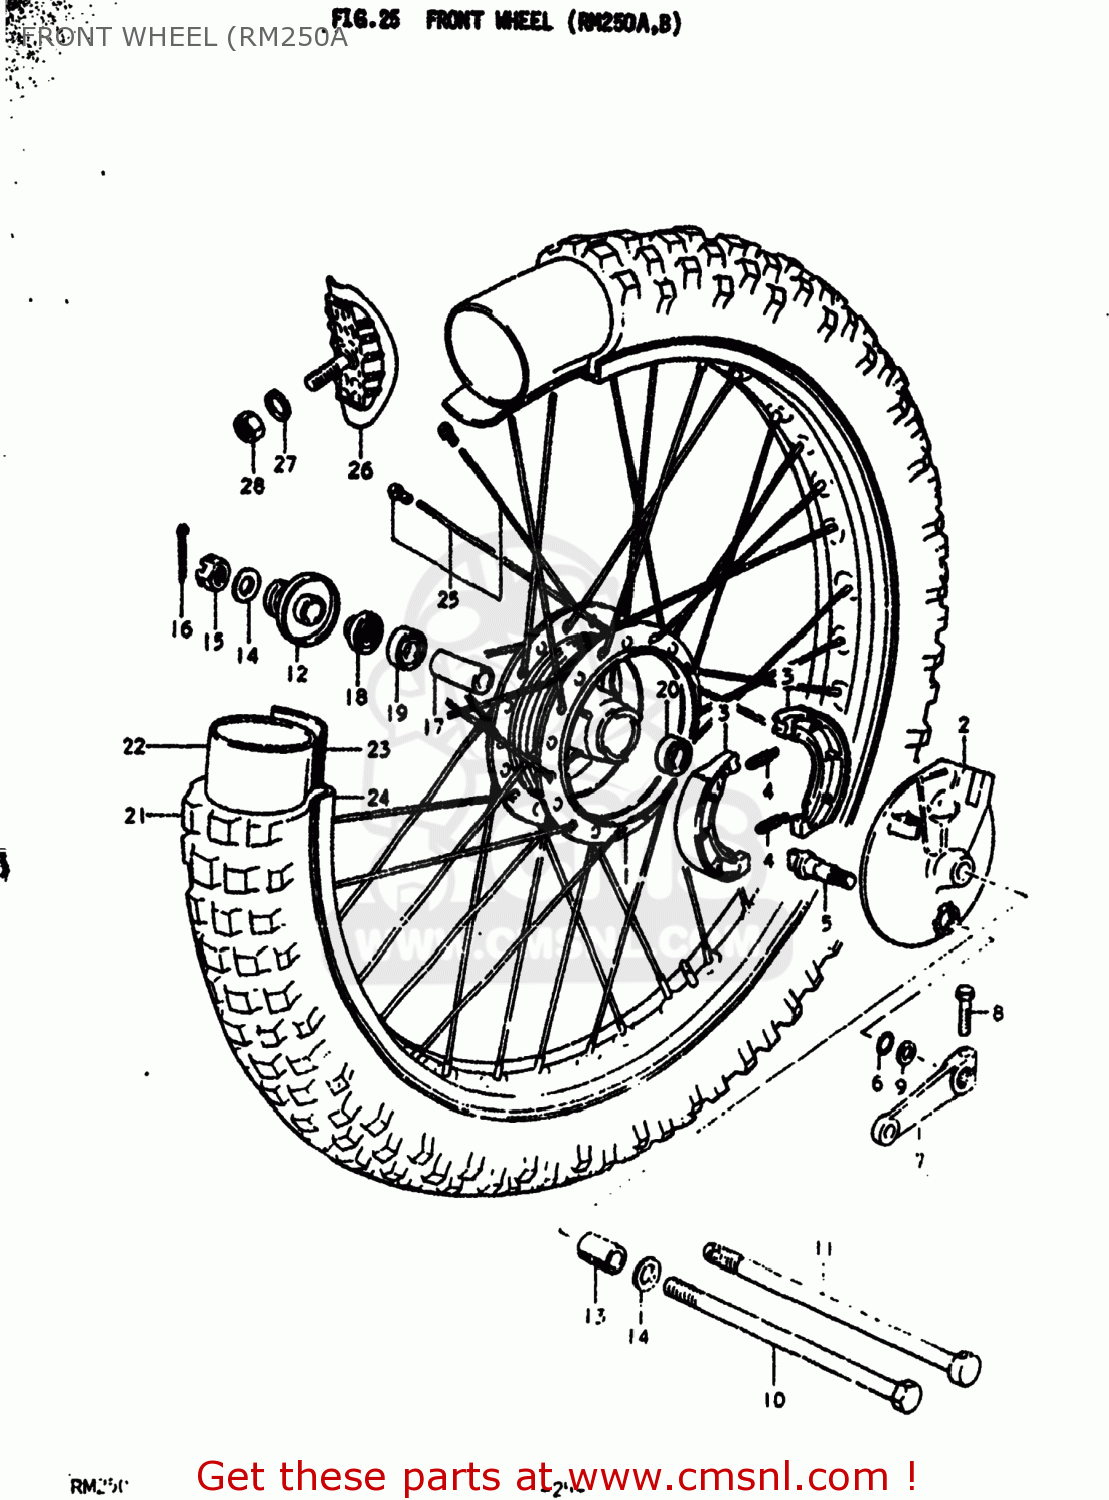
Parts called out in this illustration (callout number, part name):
1	HUB,FRONT
2	PANEL,FRONT HUB
3	SHOE,BRAKE
4	SPRING(L:34)
5	CAM,FR BRAKE
6	O RING(D:2.5,ID:11.4)
7	LEVER,FRONT BRAKE CAM
8	BOLT
9	WASHER(12.5X20X1)
10	AXLE,FRONT
11	AXLE,REAR
12	SPACER,FRONT AXLE,RIGHT
13	SPACER
14	WASHER
15	NUT, REAR AXLE
16	COTTER PIN
17	SPACER,FRONT HUB BEARING
18	OIL SEAL(17X38X5)
19	BEARING
20	BEARING, RH
21	TIRE,FRONT
22	TUBE
23	PROTECTOR,WHEEL,INNER
24	RIM,FRONT WHEEL
25	SPOKE SET
26	STOPPER,BEAD
27	WASHER
28	NUT
